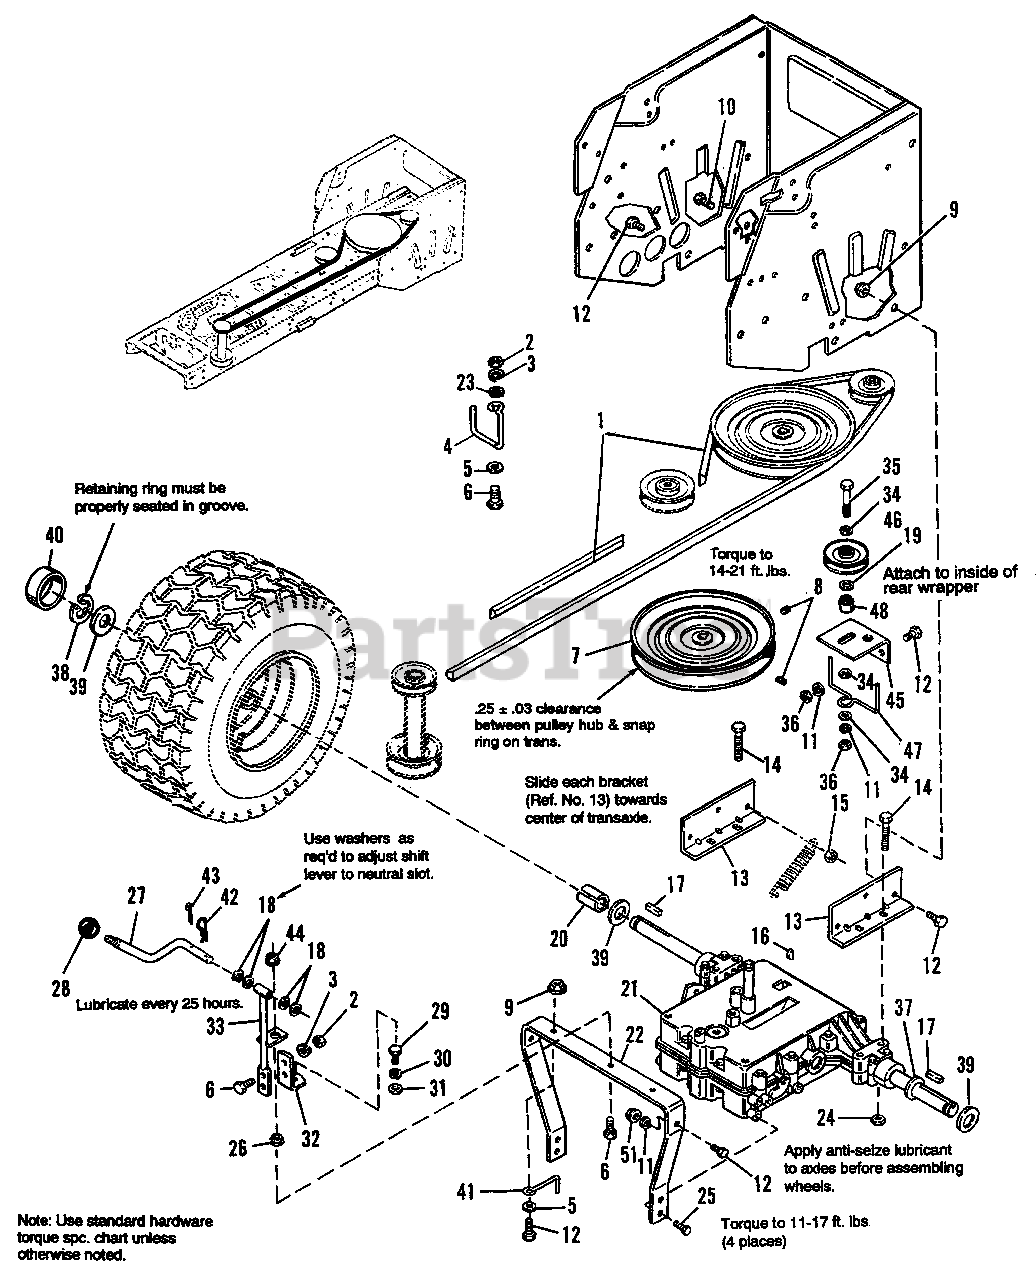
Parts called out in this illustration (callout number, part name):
2	NUT, Hex, 5/16-18
3	LOCKWASHER, 5/16
5	WASHER, 11/32
6	CAPSCREW, Hex, 5/16-18 x 1
7	PULLEY ASSY., Transmission
8	SETSCREW, 5/16-18 x 5/8
9	LOCKNUT, Hex, Flange, 3/8-16
10	CAPSCREW, Hex, 3/8-16 x 1-1/4
11	LOCKWASHER, 3/8
12	CAPSCREW, Hex 3/8 16 x 1
13	SUPPORT, Transmission, Rear
14	CAPSCREW, Hex, 5/16-18 x 2-1/2
15	LOCKNUT, Hex, 3/8 16
16	KEY, Woodruff, #9
17	KEY, 3/16 x 3/16 x 1-1/2
18	WASHER, Rev. Pinion
19	WASHER, 13/32
21	TRANSAXLE, 5 Speed
22	SUPPORT, Transmission, Front
23	LOCKWASHER, Ext.
24	LOCKNUT, 5/16-18
25	SCREW, Taptite, 5/16-18 x 5/8
26	SPACER, Special
27	ROD, Shift
28	KNOB, Ball, Shift
29	CAPSCREW, Hex, 1/4-28 x 5/8
30	LOCKWASHER, 1/4
31	WASHER, Plain
32	LINK, Shift, Lower
33	SHIFT LINK ASSY., Upper
34	WASHER
35	CAPSCREW, 3/8-16 x 2-3/4
36	NUT, Hex, 3/8-16
37	WASHER, 1/4
40	CAP, Hub, Threaded
42	PIN, Quick
43	PIN, Cotter
44	NUT, Hex, Flange Hd., 5/16-18
45	BRACKET, Pulley
46	PULLEY, Idler, "V"
